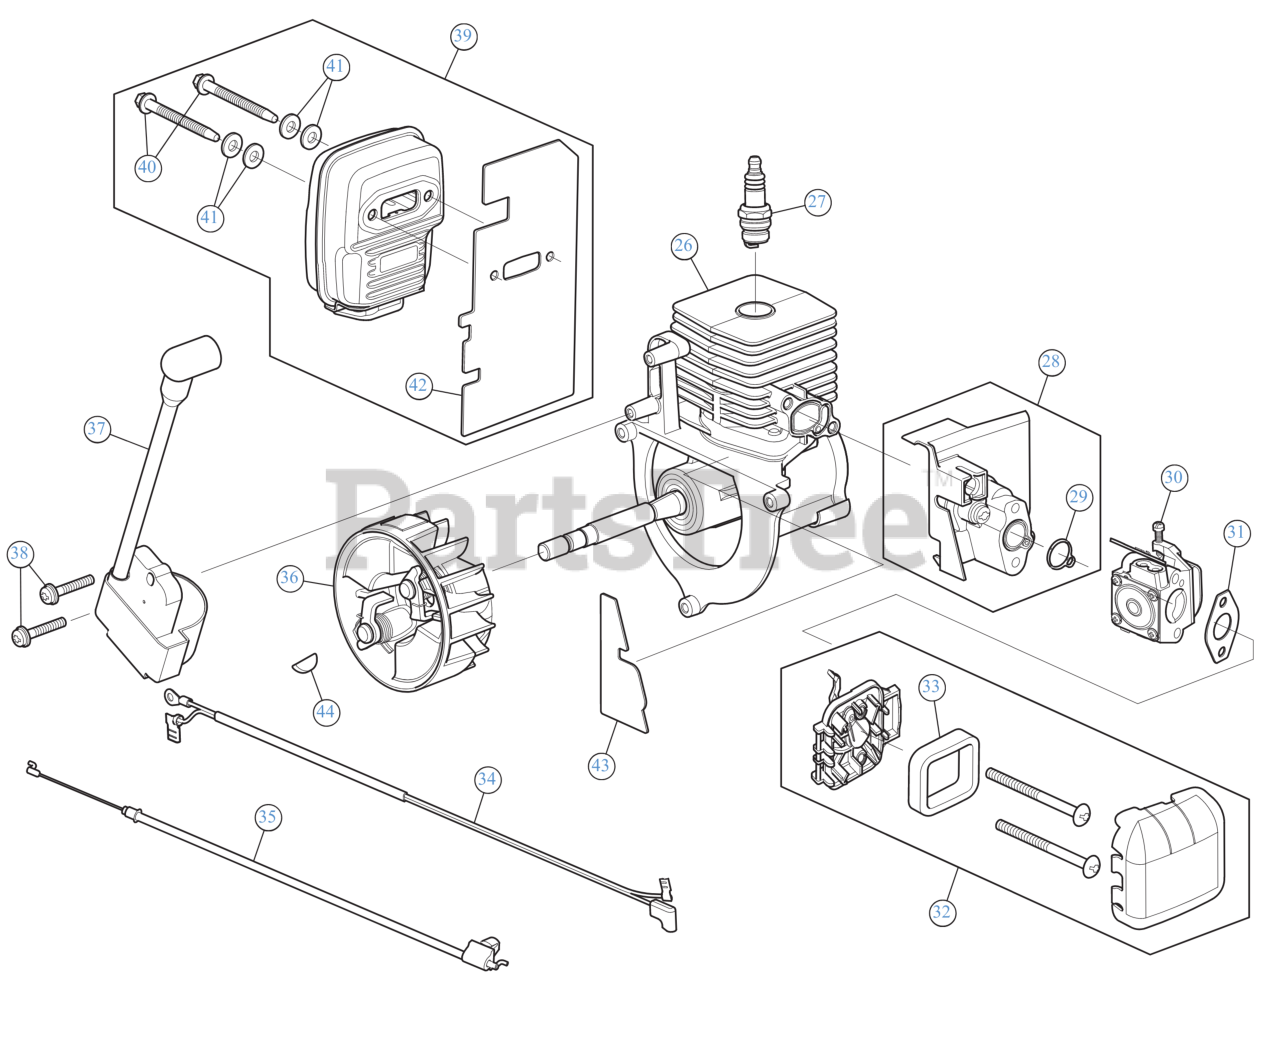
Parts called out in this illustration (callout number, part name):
26	SHORT BLOCK
27	SPARK PLUG
28	INTAKE ASSEMBLY
29	O-RING
30	CARBURETOR
31	GASKET CARB
32	AIR CLEANER ASSEMBLY
33	AIR FILTER
34	WIRE LEAD
35	THROTTLE CABLE
36	FLYWHEEL ASSEMBLY
37	MODULE
38	SCREW 8-32X.750
39	MUFFLER ASSEMBLY
40	MUFFLER SCREW
41	WASH, FLAT .480X.1
42	GASKET
43	SHORTBLOCK GASKET
44	WOODRUFF KEY #403-.125 x .375
